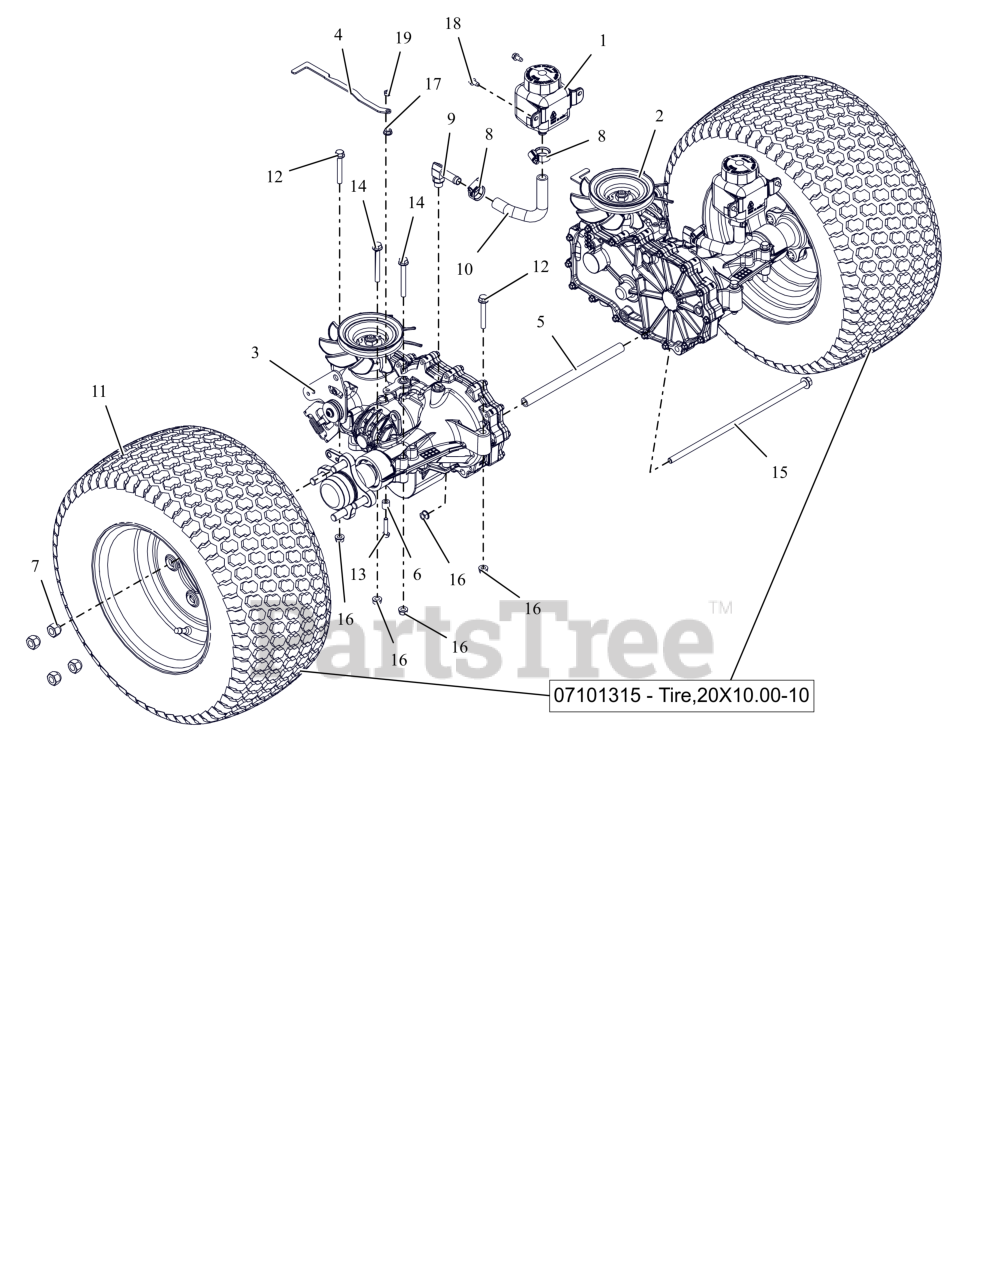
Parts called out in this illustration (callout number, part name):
1	TANK, EXPANSION
2	TRANSAXLE,ZT2800 LH
3	TRANSAXLE,ZT2800 RH
4	BRKT, DUMP VALVE
5	SPCR, TRANSAXLE .406 ID X .630 OD X 9.27 (BLACK)
6	BSHG-SLV .265X.500X.500
7	NUT, WHEEL .50-20 ZCC
8	CLAMP,.88 DIA. HOSE
9	FITTING, HYD (90 DEG)
10	HOSE, FORMED LH XL
11	ASSM TIRE\WHEEL, 20 X 10.00 - 10
11	TIRE, 20X10.00-10 (MONITOR)
12	BLT,HEX-FLG .31-18X2.25 G5 ZCC
13	BLT, HEX .25-20X1.25 G5 ZCC
14	BLT,HEX-FLG .31-18X2.75 G5 ZCC
15	BLT, HEX-FLG 0.375-16X13 GR5 ZC120
16	NUT,LK-CTR-FLG .31-18 GF ZCC
17	NUT-SPNLK-FLG .25-20 ZC120
18	SCR-TAP .25-20X.50 HWH ZCC
19	NUT-LK-CTR JAM .25-20 YWZC
